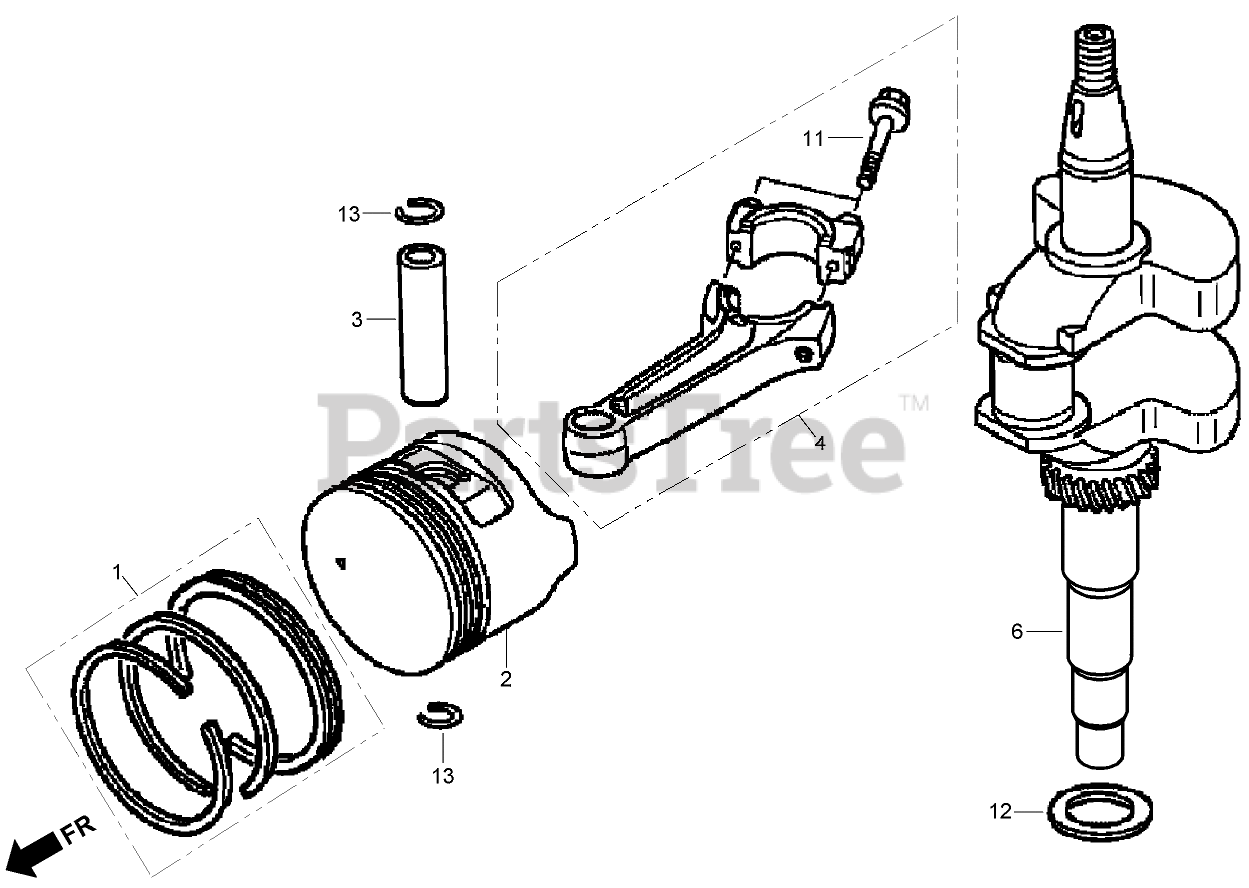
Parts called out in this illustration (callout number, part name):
1	PISTON RING SET (STD) (TEIKOKU) (Engine Serial No. Up To 1036455)
1	PISTON RING SET (STD) (NIPPON) (Engine Serial No. Up To 1036455)
1	PISTON RING SET (STD) (TEIKOKU) (Engine Serial No. From 1036456)
1	PISTON RING SET (STD) (RIKEN) (Engine Serial No. From 1036456)
1	PISTON RING SET (O S 0.25) (TEIKOKU) (Engine Serial No. Up To 1036455)
1	PISTON RING SET (O S 0.25) (NIPPON) (Engine Serial No. Up To 1036455)
1	PISTON RING SET (O S 0.25) (TEIKOKU) (Engine Serial No. From 1036456)
1	PISTON RING SET (O S 0.25) (RIKEN) (Engine Serial No. From 1036456)
1	PISTON RING SET (O S 0.50) (TEIKOKU) (Engine Serial No. Up To 1036455)
1	PISTON RING SET (O S 0.50) (NIPPON) (Engine Serial No. Up To 1036455)
1	PISTON RING SET (O S 0.50) (TEIKOKU) (Engine Serial No. From 1036456)
1	PISTON RING SET (O S 0.50) (RIKEN) (Engine Serial No. From 1036456)
1	PISTON RING SET (0.75) (TEIKOKU) (Engine Serial No. Up To 1036455)
1	PISTON RING SET (0.75) (NIPPON) (Engine Serial No. Up To 1036455)
1	PISTON RING SET (0.75) (TEIKOKU) (Engine Serial No. From 1036456)
1	PISTON RING SET (0.75) (RIKEN) (Engine Serial No. From 1036456)
2	PISTON (STD) (Engine Serial No. Up To 1036455)
2	PISTON (STD) (JIALING-HONDA) (Engine Serial No. From 1036456)
2	PISTON (O S 0.25) (Engine Serial No. Up To 1036455)
2	PISTON (O S 0.25) (Engine Serial No. From 1036456)
2	PISTON (O S 0.50) (Engine Serial No. Up To 1036455)
2	PISTON (O S 0.50) (Engine Serial No. From 1036456)
2	PISTON (0.75) (Engine Serial No. Up To 1036455)
2	PISTON (0.75) (Engine Serial No. From 1036456)
3	PIN-PISTON
4	CONNECTING ROD ASM
6	CRANKSHAFT
11	BOLT-ROD, CONNECTING
12	WASHER-THRUST (25.6 mm)
13	CLIP-PIN, PISTON (18 mm)
